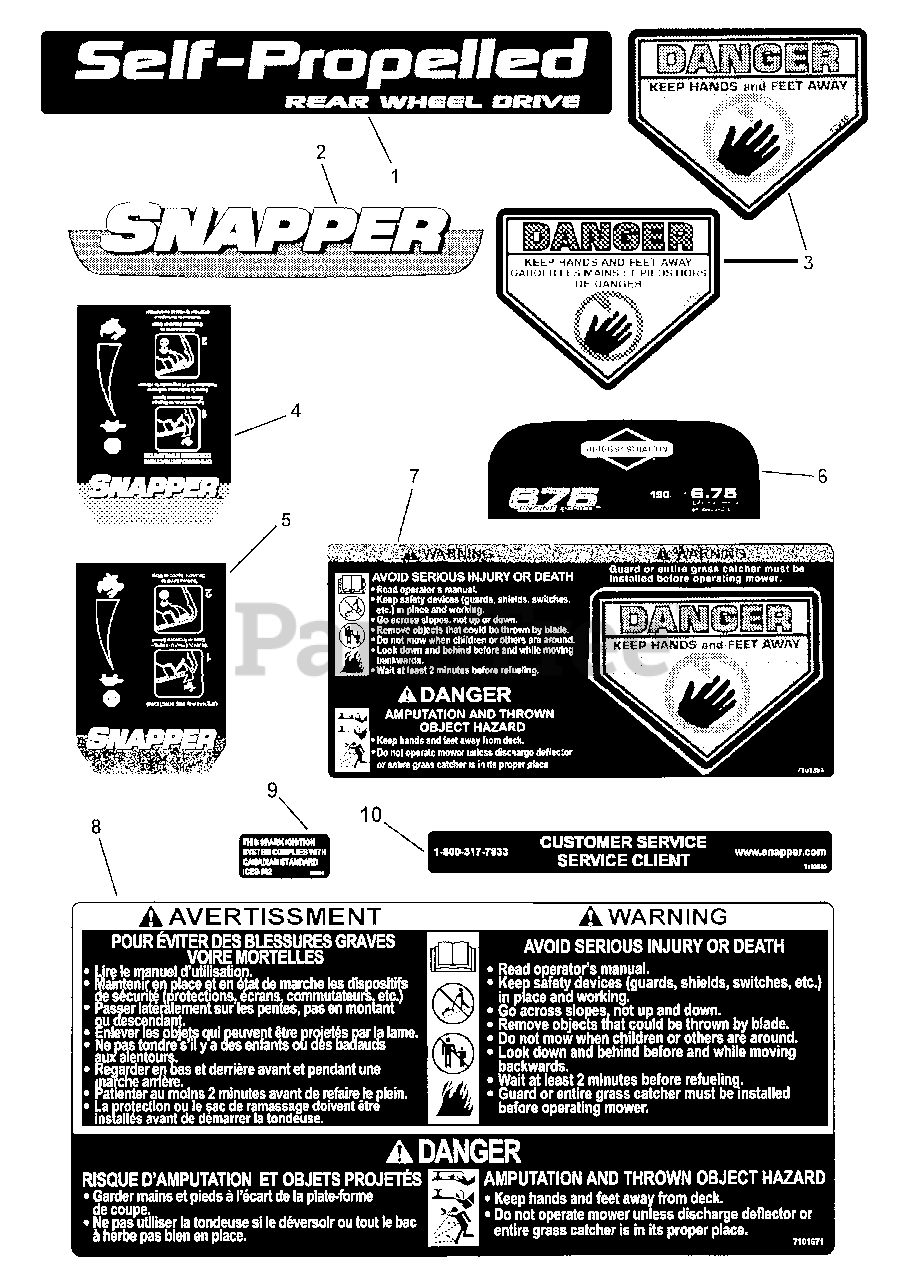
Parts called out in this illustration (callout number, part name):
1	DECAL, Front Cover, 21" RD, Snapper
2	DECAL, Briggs Engine, Snapper
3	DECAL, Danger, Cut Finger
3	DECAL, CPSC, French/English
4	DECAL, Control Head, VS, Snapper, FC
5	DECAL, Control Head, VS, Snapper
6	DECAL, Engine, TP, 675, Snapper, FC
7	DECAL, Warning, Rear Discharge Door
8	DECAL, WB Safety, French/English
9	DECAL, Customer Service Snapper FC
10	DECAL, Compliance, ICES
